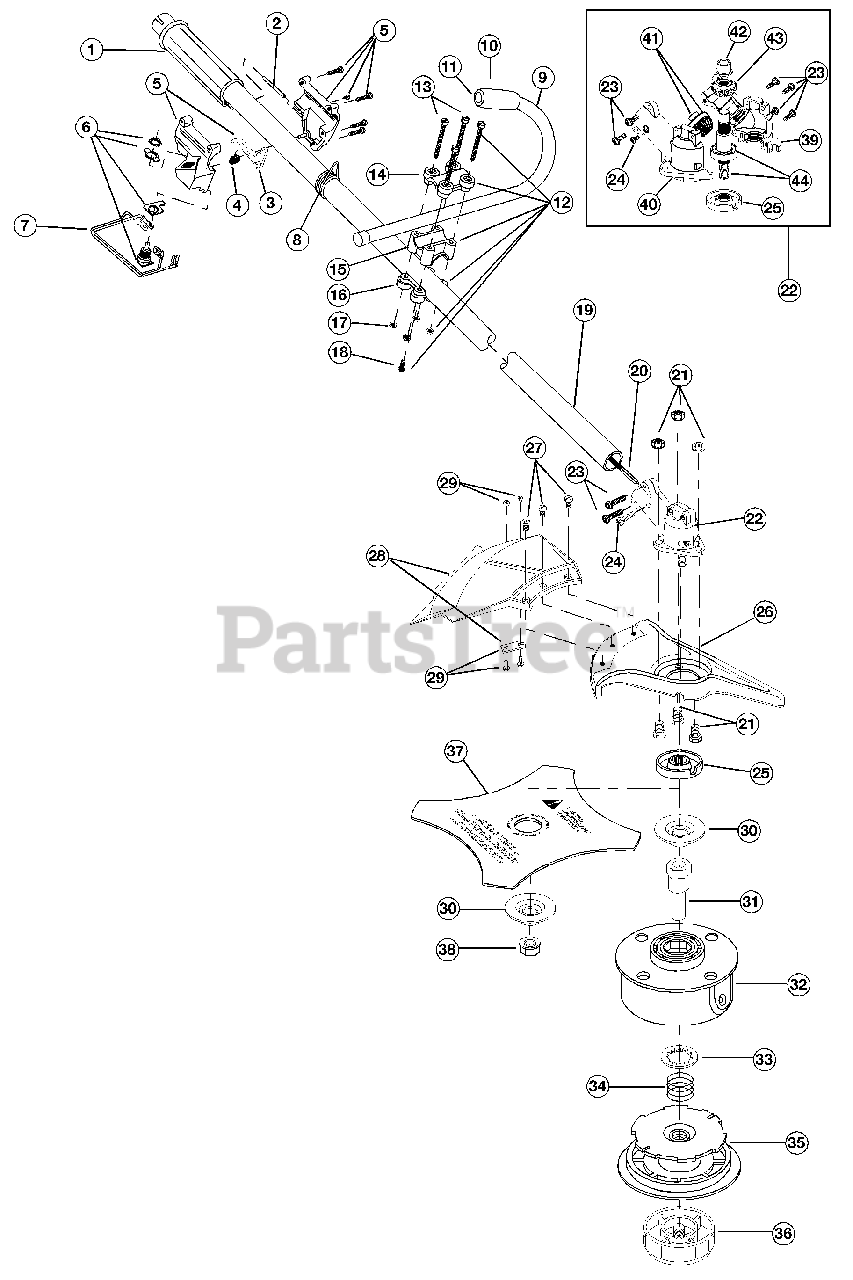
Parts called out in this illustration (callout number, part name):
2	Throttle Cable Assembly
3	Throttle Trigger
4	Throttle Trigger Spring
5	Throttle Trigger Assembly
6	Switch Assembly
7	Wire Lead Assembly
8	Shoulder Harness Clamp
9	J-Handle Assembly
11	Tube Closure
12	Handle Bracket Assembly
14	Upper Handle Clamp
15	Middle Handle Clamp
16	Lower Handle Clamp
18	Anti-Rotation Screw
19	Drive Shaft Housing Assembly
20	Flexible Drive Shaft
21	Shield Mount Screw Assembly
22	2 piece Gearbox Assembly
23	Gearbox Mounting Hardware
24	Anti-Rotation Screw
25	Blade Driver
26	Blade Shield/Shield Mount
27	Shield Mounting Screw
28	Shield and Blade Assembly
29	Blade Assembly
30	Retaining Washer
31	Spool Shaft
32	Outer Spool and Eyelet Assembly
33	Retainer
34	Spring
36	Bump Head Knob Assembly
38	Nut
39	Left Housing
40	Right Housing
41	Pinion Gear Assembly
42	Output Shaft Bushing
43	Output Shaft Gear
44	Output Shaft Assembly
